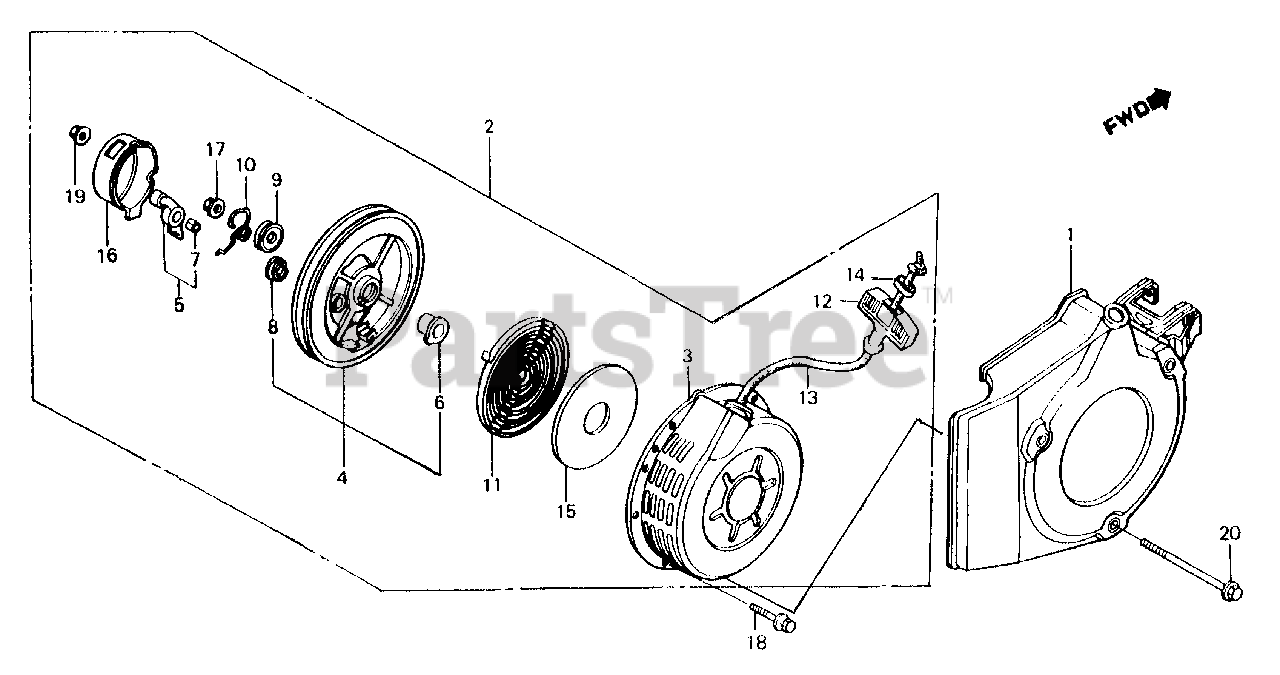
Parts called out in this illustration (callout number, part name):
1	COVER, RECOIL *R8* (BRIGHT RED) (NOT AVAILABLE)
2	STARTER ASSY., RECOIL (NOT AVAILABLE)
3	CASE, STARTER
4	REEL, STARTER
6	BOSS, REEL
7	BUSH, RATCHET
8	BUSH, REEL STARTER
9	PLATE, FRICTION
10	SPRING, FRICTION
11	SPRING, RETURN
12	GRIP, STARTER
13	ROPE, RECOIL STARTER (#5X55")
14	SUPPORT, GRIP
15	PLATE, SIDE
16	COVER, REEL STARTER
17	NUT, SELF-LOCK (8MM)
18	BOLT-WASHER (6X10)
19	NUT, FLANGE (5MM)
20	BOLT, FLANGE (6X70)
